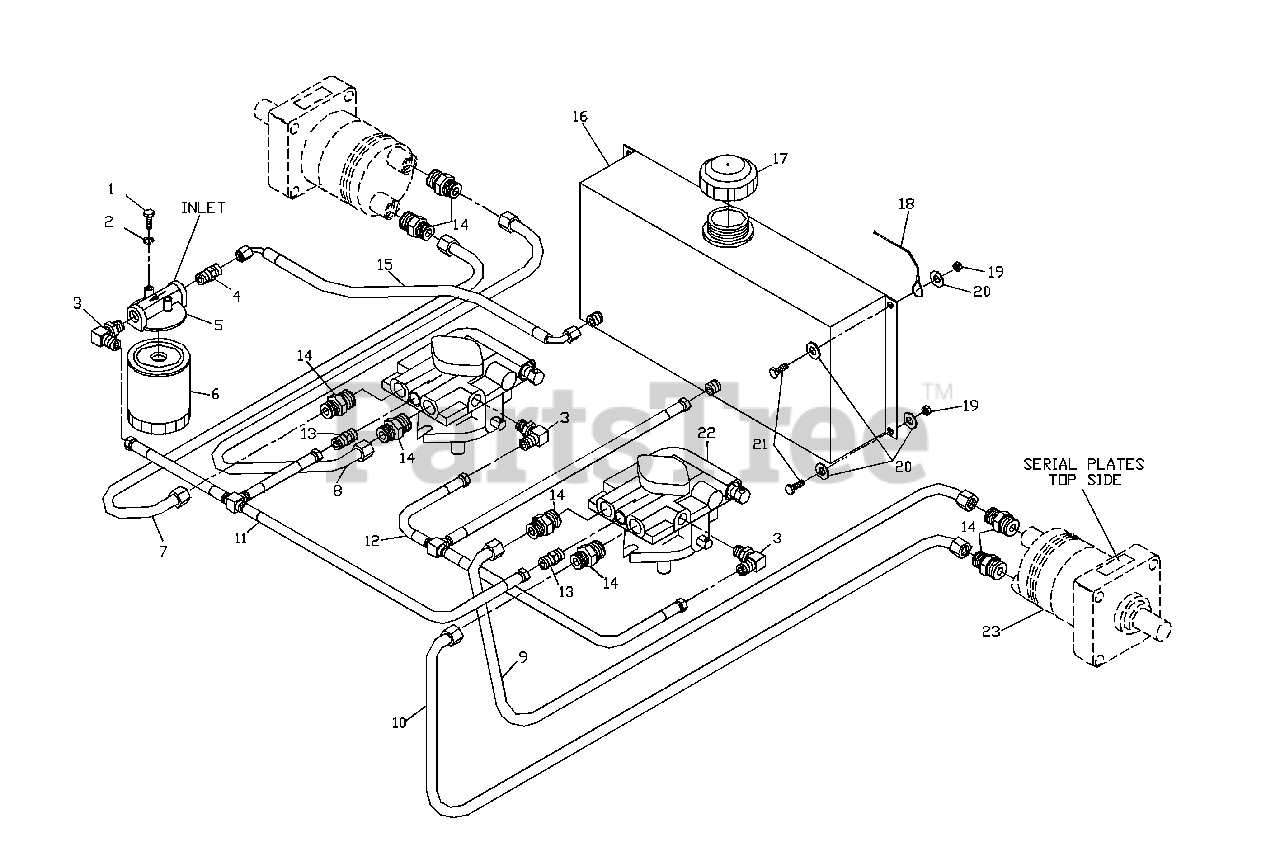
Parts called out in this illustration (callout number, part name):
1	HCS 1/4C X 5/8
2	1/4" LOCKWASHER
3	F6801-6-6-0 90 DEG. ELBOW
4	F6400-6-6-0 STRAIGHT FITTING
5	FILTER HEAD
7	RIGHT OUTSIDE TUBE
8	RIGHT INSIDE TUBE
9	LEFT INSIDE TUBE
10	LEFT OUTSIDE TUBE
11	SUCTION TEE ASSEMBLY
12	RETURN TEE ASSEMBLY
13	F6400-6-4-0 STRAIGHT FITTING
14	F6400-8-8-0 STRAIGHT FITTING
16	TANK, HYDRAULIC
17	HYDRAULIC CAP
18	SEAT LANYARD
19	NUT 1/4C CENTERLOCK
20	WASHER 1/4 FLAT
21	HCS 1/4C X 1
23	WHEEL MOTOR
